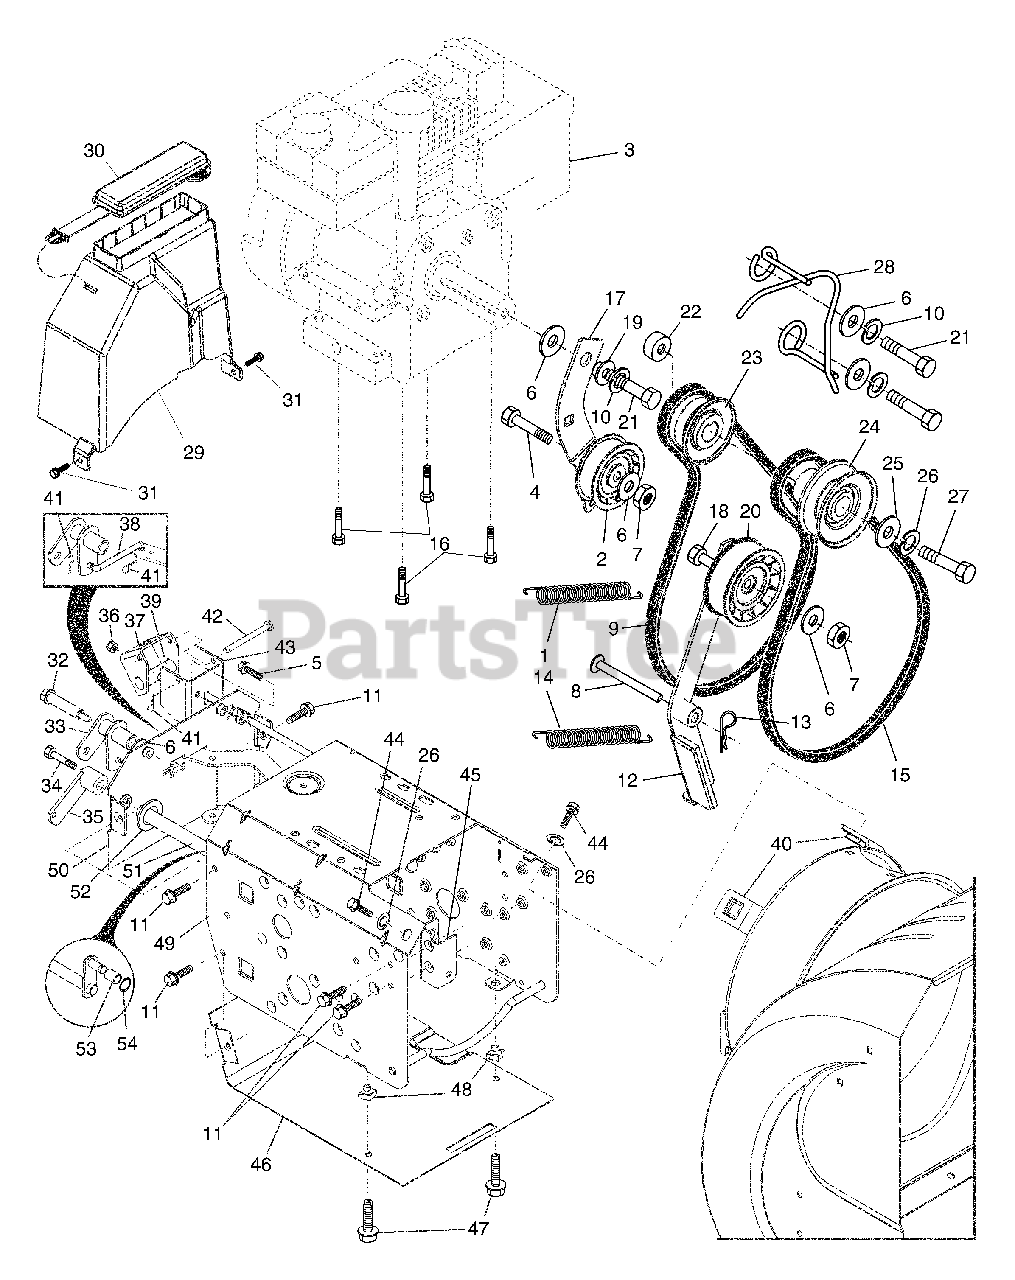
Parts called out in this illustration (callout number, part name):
1	Spring, Traction Idler
2	Pulley, Idler (2-1/4)
4	Screw, Hex Head 5/16-18 x 1-1/4
5	Screw, Hex Head 5/16-18 x 3/4
6	Washer, Flat
7	Nut, Jam, Lock 5/16-18
8	Pin, Idler Pivot
9	V-Belt, Traction Drive
10	Washer, Lock 5/16
11	Screw, Hex Head 5/16-18 x 1/2
12	Impeller Idler Arm Assembly
13	Retainer, Hairpin
14	Spring, Brake
15	V-Belt, Impeller Drive
16	Screw, Hex Head 3/8-16 x 1-1/4
17	Arm, Idler
18	Screw, Hex Head 5/16-18 x 1-1/2
19	Bushing, Idler Pivot
20	Pulley, Idler (2-3/4)
21	Screw, Hex Head 5/16-18 x 1
22	Spacer, Engine Pulley
23	Pulley, Engine, Traction Drive
24	Pulley, Engine, Impeller Drive
25	Washer, Flat 3/8
26	Washer, Lock, Helical 3/8
27	Screw, Hex Head 3/8-24 x 1-3/8
28	Guide, Belt
29	Cover, Belt
30	Cover, Toolbox
31	Screw, Hex Head 1/4-20 x 1/2
32	Bolt, Shoulder 5/16-18
33	Bellcrank Shifter
34	Screw, Hex Head 1/4-28 x 3/4
35	Arm, Auger Control
36	Nut, Lock 5/16-18
37	Bellcrank Assembly
38	Link, Speed Control
39	Trunnion, Pivot Bracket
40	Nut, Cage 3/8-16
41	Hairpin, Cotter 3/32 x 1/2
42	Pin, Pivot Bracket
43	Bracket, Bellcrank
44	Screw, Hex Head 3/8-16 x 1-1/2
45	Pivot Bracket, Impeller Idler Arm
46	Pan, Frame Bottom
47	Screw, Hex Head 5/16-18 x 3/4
48	Nut, Speed 5/16-18
49	Frame Assembly
50	Plate, Frame End
51	Shaft, Auger Control
52	Washer, Hardened
54	Ring, Retaining
